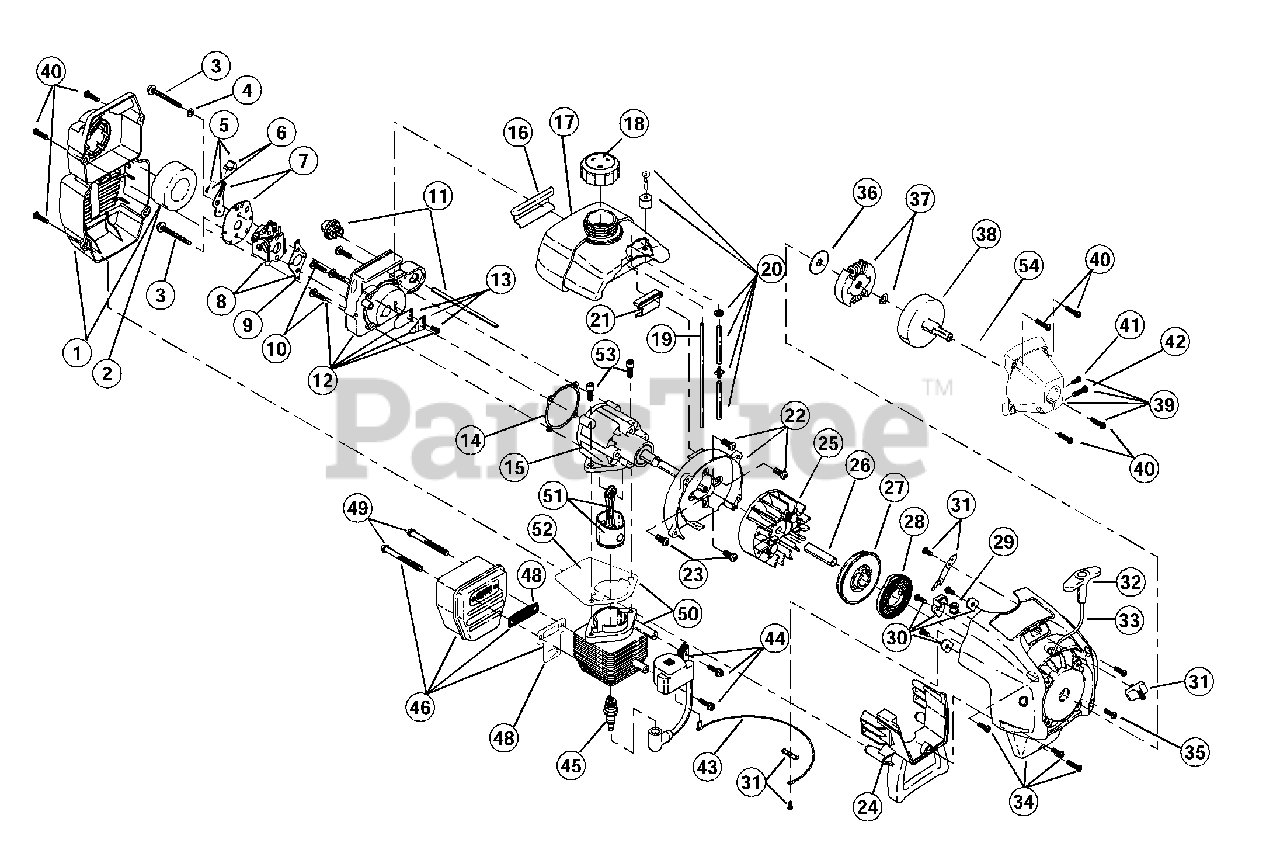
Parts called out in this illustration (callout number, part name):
1	Air Cleaner/Muffler Cover Assembly
2	Air Cleaner Filter
3	Carburetor Mounting Screw Assembly
4	Wavey Washer
5	Choke Lever Assembly
6	Choke Knob and Screw
7	Choke Lever and Plate
8	Carburetor Assembly
9	Carburetor Gasket
10	Carb Mount Screw
11	Primer and Hose Assembly
12	Carb Mount Assembly
13	Reed Assembly
14	Carburetor Mount Gasket
15	Crank Case Service Assembly
16	Rear Mounting Pad
17	Fuel Tank Assembly
18	Fuel Cap Assembly
19	Fuel Return Line
20	Fuel Line Assembly
21	Front Mounting Pad
22	Shroud Assembly
23	Shroud Screw
24	Shroud Extension and Stand
25	Flywheel Assembly
27	Recoil Pulley Assembly
28	Recoil Spring
29	Rope Guide
30	Pulley Retainer Assembly
31	Switch Assembly
32	Pull Handle
34	Starter Housing Assembly
35	Housing Screw
36	Clutch Washer
37	Clutch Rotor Assembly
38	Clutch Drum Assembly
39	Clutch Cover Assembly
40	Cover Screw
41	Anti-Rotation Screw
42	Wire Lead
43	Module Assembly
44	Spark Plug
45	Muffler Assembly
46	Spark Arrestor Screen
47	Exhaust Gasket
48	Muffler Mounting Bolt Assembly
49	Cylinder Assembly
50	Piston and Rod Assembly
51	Cylinder Gasket
52	Cylinder Bolt
